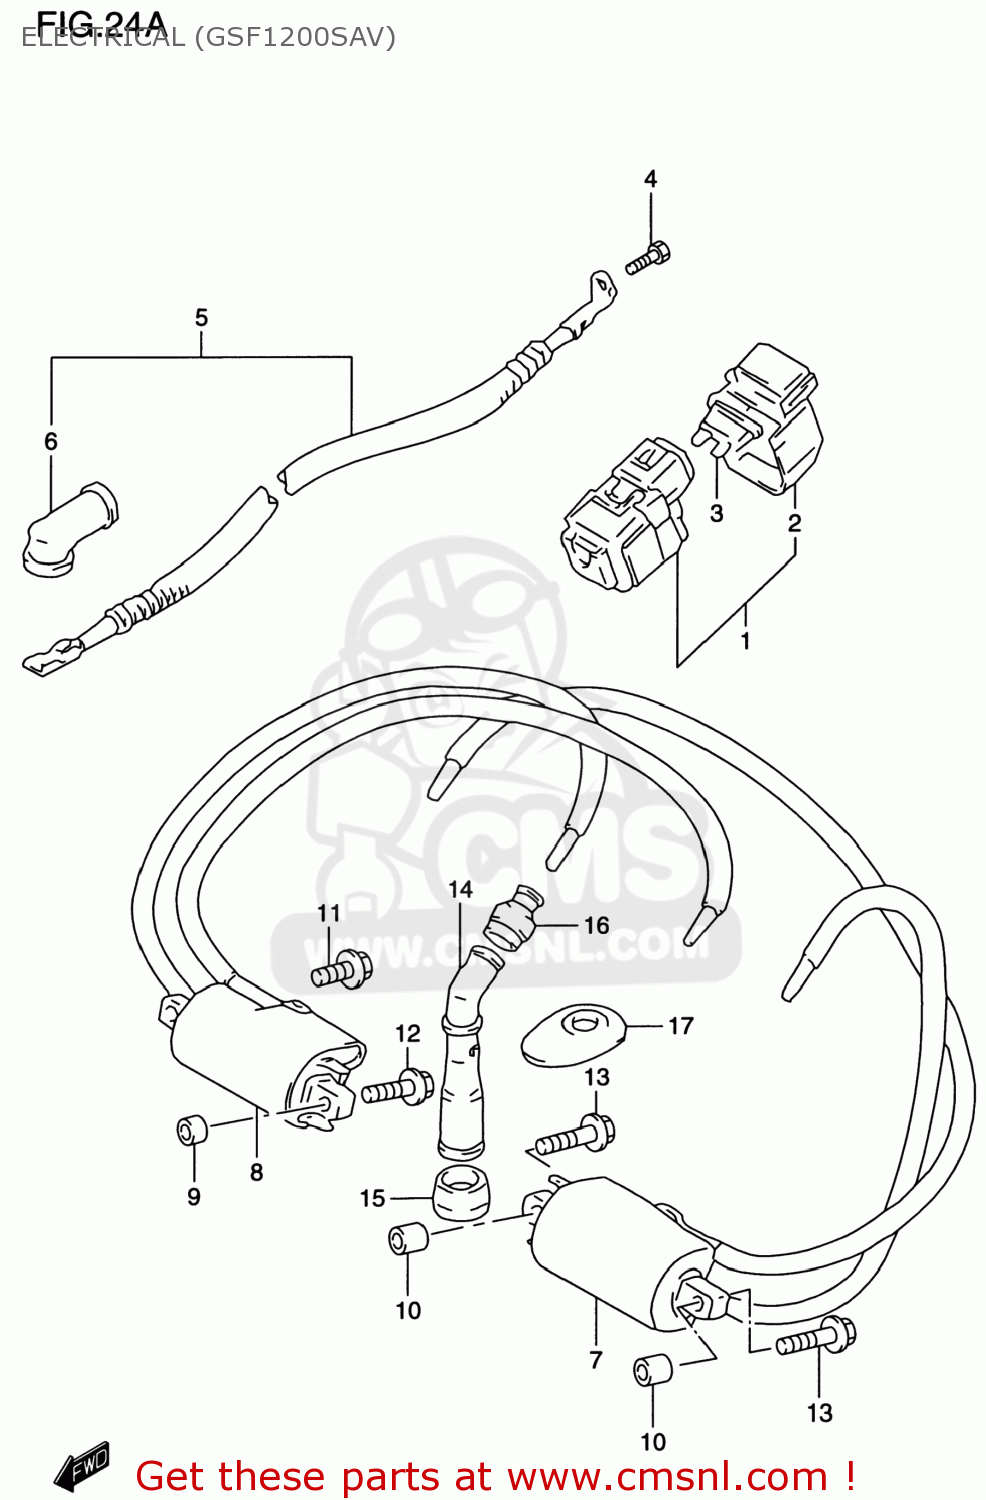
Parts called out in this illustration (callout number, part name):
1	RELAY ASSY,STARTING MOTOR
2	COVER,STARTER RELAY
3	FUSE(30A)
4	SCREW(6X8)
5	WIRE,STARTER MOTOR LEAD
6	CAP,STARTER MOTOR LEAD
7	COIL ASSY,IGNITION
8	COIL ASSEMBLY,IGNITION
9	SPACER(6X12X10)
10	SPACER(6.2X12X16)
11	BOLT
12	BOLT
13	BOLT
14	CAP,SPARK PLUG
15	SEAL,SPARK PLUG CAP
16	SEAL,HIGH TENSION CORD
17	COVER,SPARK PLUG CAP
